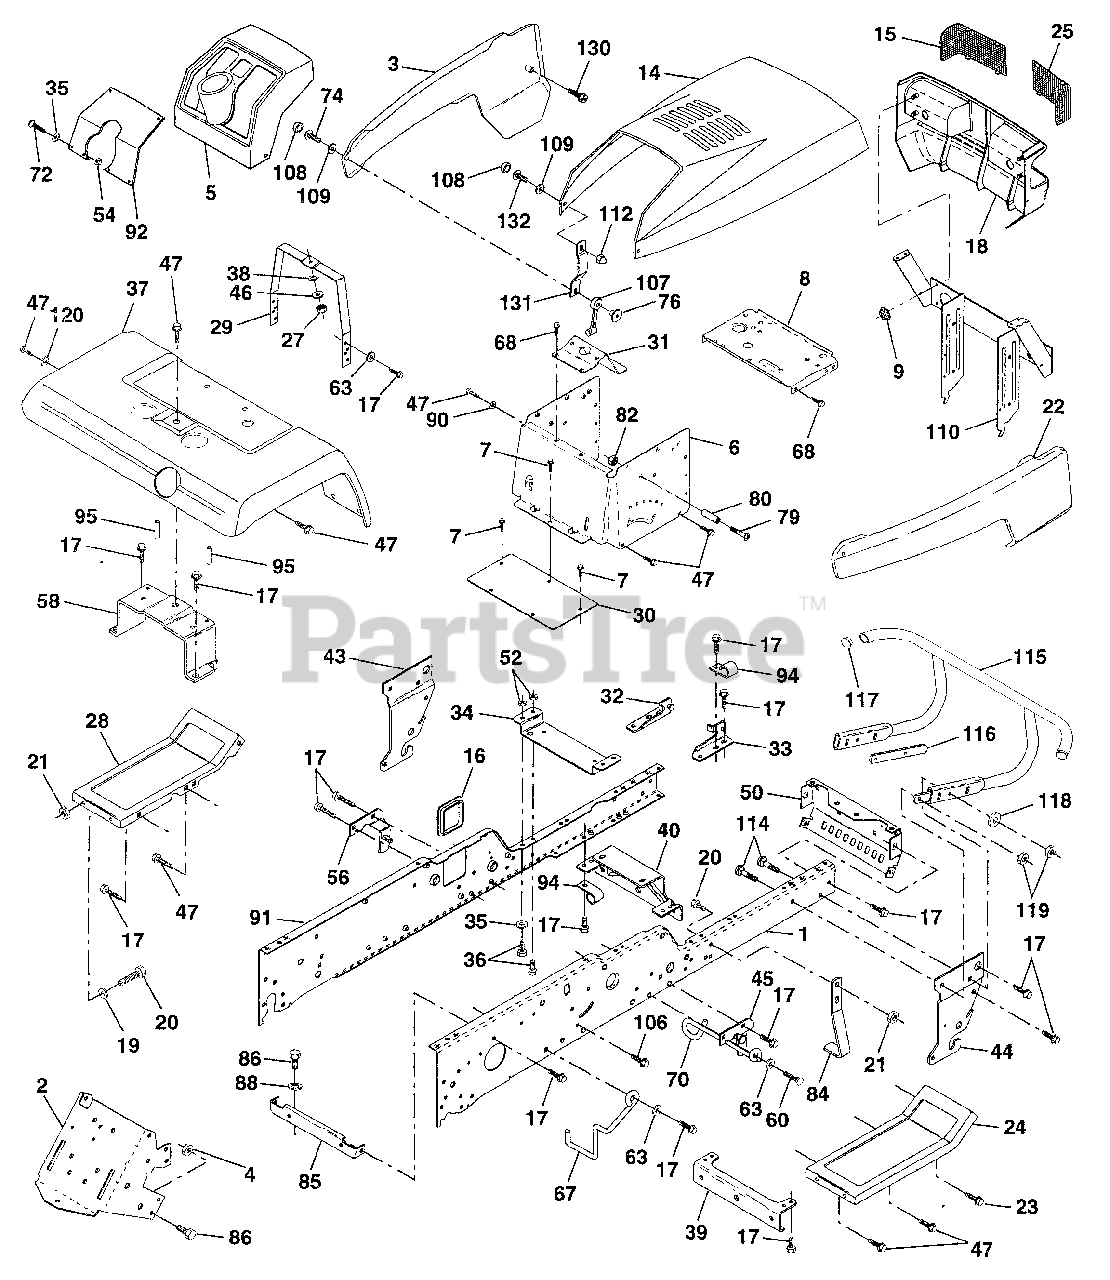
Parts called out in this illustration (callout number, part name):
1	Rail, Frame RH
2	Drawbar, Gt
3	Panel Asm., Side LH
4	Nut, Lock Hex 7/16 Unc
5	Dash, Plastic Black
6	Dash 1-PCS, Lower
7	Screw, Thd Cut 1/4-20 x 1/2
8	Support, Battery
14	Hood Asm., Pnt
15	Lens, Headlight LH
16	Cover, Access
17	Screw, Thdrol 3/8-16 x 3/4
18	Grille
19	Washer 13/32 x 13/16 x 12 Ga.
20	Bolt, Fin Hex 3/8-16 x 1
21	Nut, Crownlock 3/8-16 Unc
22	Panel Asm., Side RH
23	Screw Thdrol. 3/8-16 x 1 Ty-TT
24	Footrest, RH
25	Lens Headlight RH
27	Nut Fin Hex 1/4-20
28	Footrest, LH
29	Bracket, Support Dash
31	Brace, Support Steering
32	Bracket Asm., Frame Pivot Lh
33	Bracket Asm., Frame Pivot Rh
34	Bracket, Engine Support Rear
35	Washer 11/32 x 11/16 x 16 Ga.
36	Bolt, Fin Hex 5/16-18 x 3/4
37	Fender, Pnt.
38	Washer, Lock 1/4
39	Bracket, Axle Front
40	Bracket, Support Axle/Engine
43	Bracket, Spnsn Front Lh
44	Bracket, Spnsn Front Rh
45	Bracket Asm., Susp Chassis Rh
46	Washer 9/32 x 3/4 x 16 Ga.
47	Screw Thdrol 3/8-16 x 1/2
50	Bracket, Chassis Front
52	Locknut, Hex W/Ins 5/16-18 Unc
54	Nut 5/16-18
56	Bracket Asm., Susp Chassis Lh
58	Bracket Asm., Fender
60	Screw Thdrol 3/8-16 x 1-1/4
63	Washer 13/32 x 1 x 14 Ga.
67	Guide Belt Trans VGT
68	Screw, Thdrol 5/16-18 x 1/2
70	Guide, Belt Mid Span
72	Screw, Mach Trhd 5/16-18 x 3/4
74	Screw, Machine #10-24
76	Nut, Weld #10-24
79	Screw, Machine #10-24 x 1/4
80	Spacer, Split
82	Nut #10-24
84	Stop, Over Center 44" 20/23" T. 94
85	Bracket Support Pnt Trans VGT
86	Bolt, Fin Hex 7/16-14 Unc x 1
88	Washer Lock Hvy Hlcl Spr 7/16
90	Washer, Lock External Tooth 3/8
91	Rail, Frame Lh
92	Plate, Silkscreen Dash
94	Clip, Fuel Line
95	Push Nut, Nylon
106	Screw Thdrol. Hex Hd Zinc Mur
107	Latch, Chute Blk
108	Cap, Snap Black
109	Cap, Washer Snap
110	Pivot Asm. Grille/Hood Husq. VGT
112	Nut, Acorn, Hex #10-24
114	Bolt, Carriage 3/8-16 x 1-1/4
115	Bumper Asm.
116	Bracket Extension Bumper
117	Plug Plastic
118	Washer 13/32 x 13/16 x 16 Ga.
119	Nut Crownlock 3/8-16 UNC
120	Washer 13/32 x 1 x 16 Ga.
130	Screw, SLTD Hex Hd. W/Pl Washer
131	Bracket Support Hood/Panel YP
132	Screw, Truss Hd. #10-24 x 3/8
